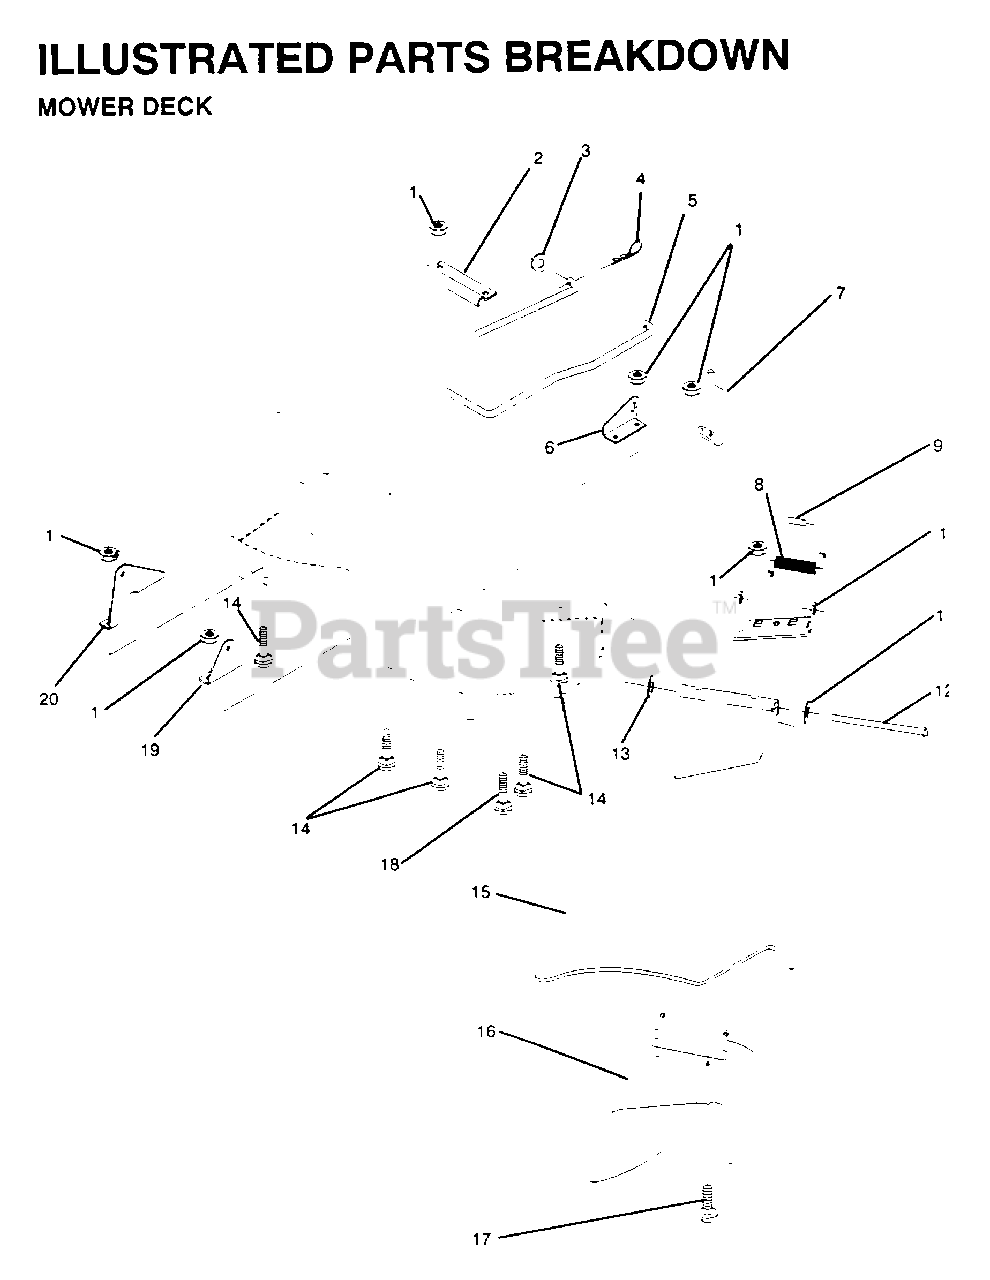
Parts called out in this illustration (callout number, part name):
2	"BRKT,STAB LINK"
4	RETAINER.SPRING
5	STABILIZER MOWER
6	"BRKT,FRT LIFT RH"
7	"GUIDE,FRT MAN RH"
8	SPRING TORSION
9	CAP-SLEEVE LT
11	WASHER
12	HINGE ROD
13	NUT PUSH M
14	BOLT
16	DEFL SUPT ASS'Y
17	SCREW PAN HD
18	BOLT
19	"BRKT,REAR LIFT RH"
20	"BRKT,REAR LIFT LH"
